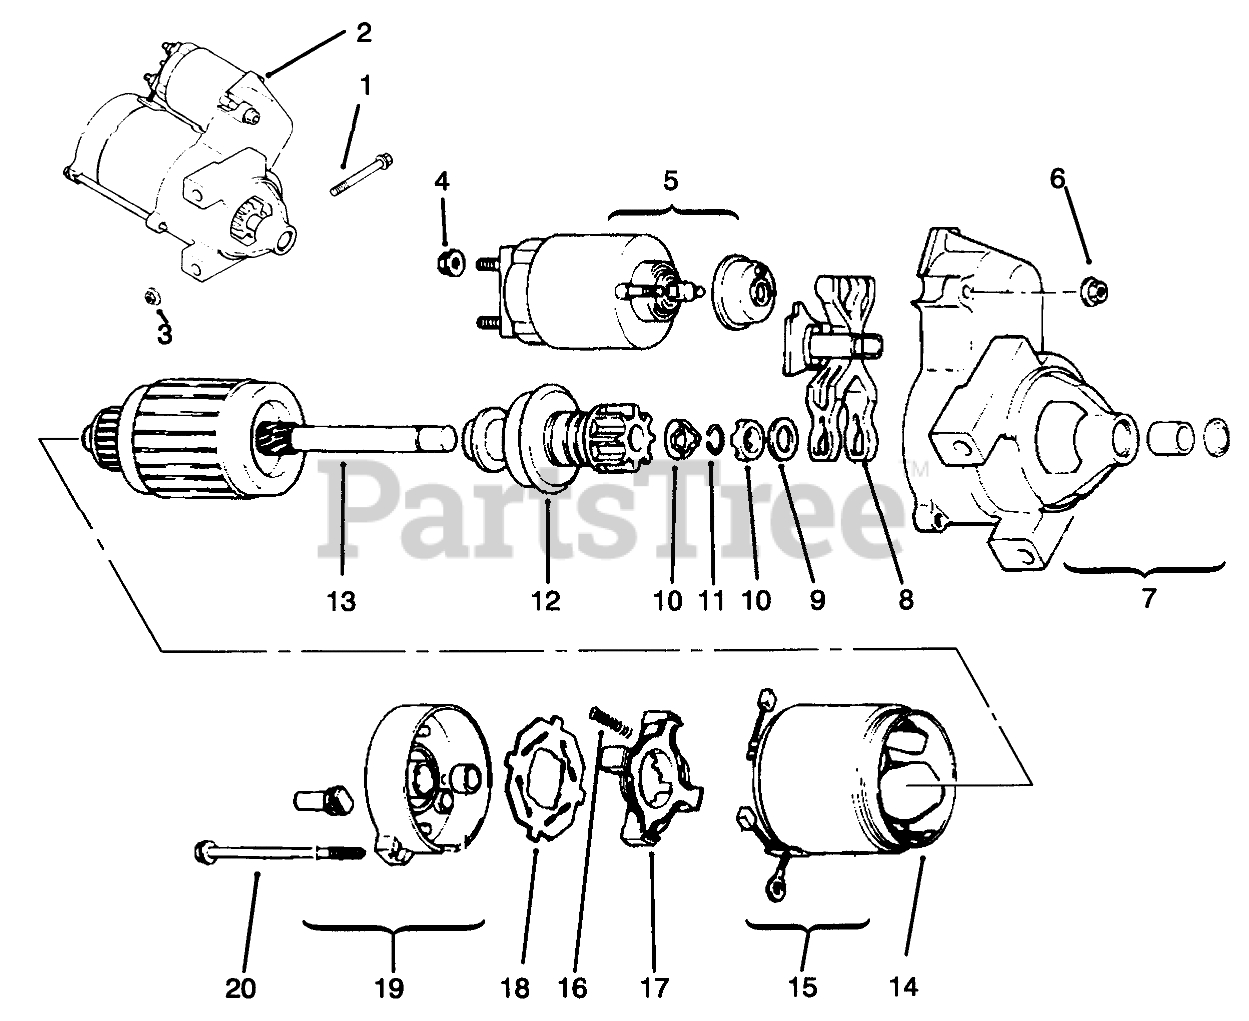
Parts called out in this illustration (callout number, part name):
2	Starter INC 4-20
4	Nut
5	Solenoid
6	Nut
7	Cap Drive End
8	Lever Starter Drive
9	Washer-Thrust
10	Nut
11	Ring-Retainer
12	Drive Pinion
13	Armature
14	Frame
15	Brush Kit
16	Spring Brush
17	Holder-Brush
18	Insulator
19	Cap-Commutator End
20	Bolt
